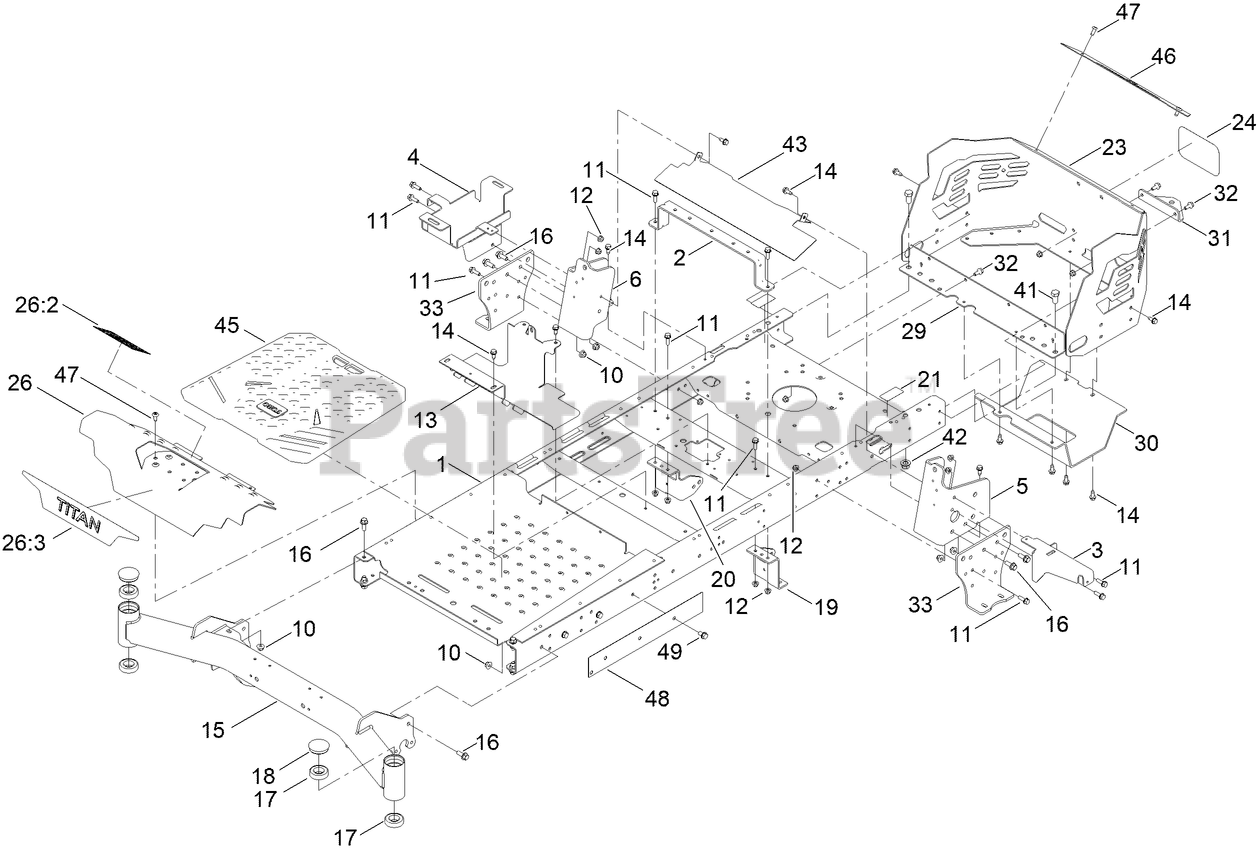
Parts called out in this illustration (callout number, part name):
1	FRAME ASM
2	BRACE-SEAT, REAR (WIDE)
3	BRACKET-SUPPORT, POD (LH)
4	TRAY-BATTERY
5	BRACKET-MOUNTING, LH
6	BRACKET-MOUNTING, RH
10	NUT-HF, NI
11	SCREW-HHF
12	NUT-HF, NI
13	BRACKET-MOUNT
14	SCREW-HWHTF
15	FRONT AXLE ASM
16	SCREW-HHF
17	BEARING-BALL
18	CAP-GREASE
19	MOUNT-HYDRO, FRONT (LEFT)
20	MOUNT-HYDRO, FRONT (RIGHT)
21	DECAL-BYPASS
23	GUARD-ENGINE
24	DECAL
26	FOOTREST-TITAN
26:2	DECAL-DANGER
26:3	DECAL-TITAN
29	CROSSMEMBER-REAR, WIDE
30	GUARD-MUFFLER
31	BRACKET-HITCH
32	SCREW-HHF
33	MOUNT-HYDRO
41	SCREW-HH
42	NUT-LOCK
45	FLOOR MAT
46	TRIM-GUARD, ENGINE
48	PLATE-FRAME
49	SCREW-HWHTF
